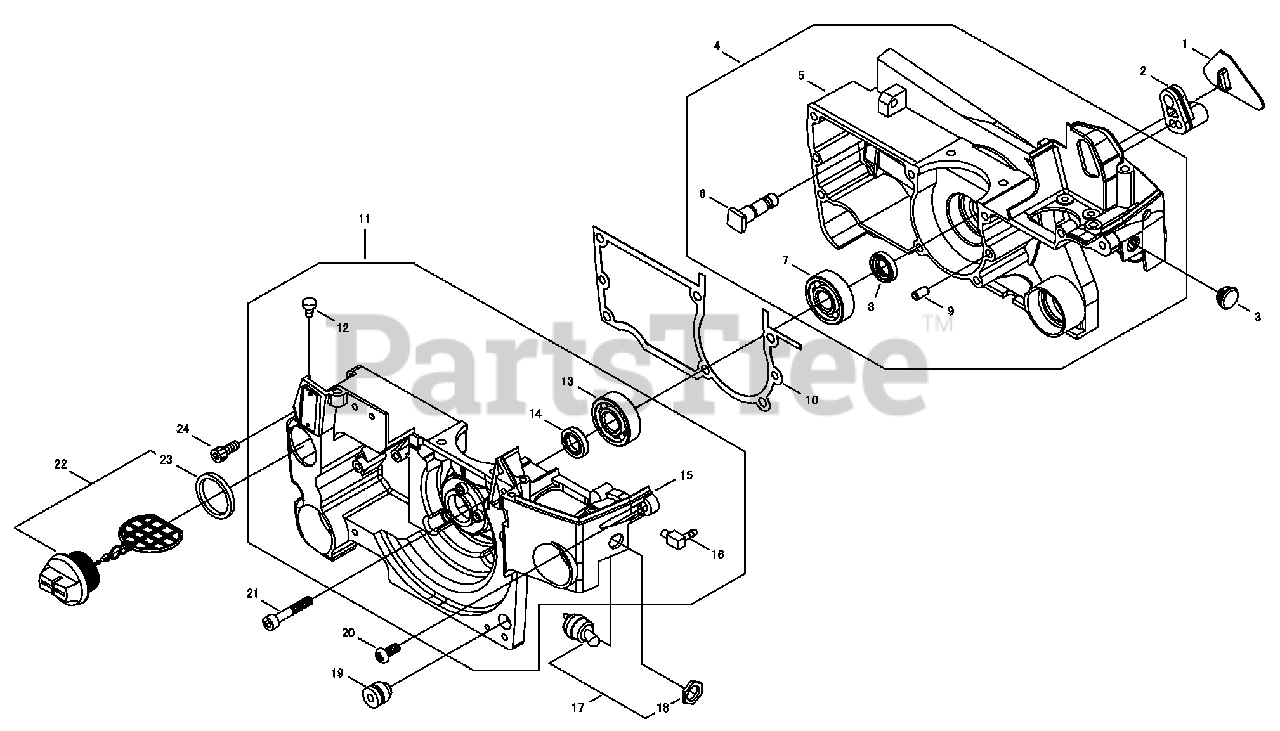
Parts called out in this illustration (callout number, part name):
1	STOPPER
2	GROMMET
3	PLUG
4	CRANKCASE ASSY
5	CRANKCASE
6	BOLT
7	BEARING, BALL 6201 C3
8	SEAL, OIL 12
9	PIN, LOCATING 5×10
10	GASKET
11	CRANKCASE ASSY
12	VENT ASSY
13	BEARING, BALL 6201 C3
14	SEAL, OIL 12
15	CRANKCASE
16	CONNECTOR, PIPE
17	SWITCH ASSY
18	NUT 10
19	SUPPORT
20	SCREW
21	BOLT M5×30
22	CAP ASSY, OIL
23	GASKET, CAP
24	BOLT M5×18
